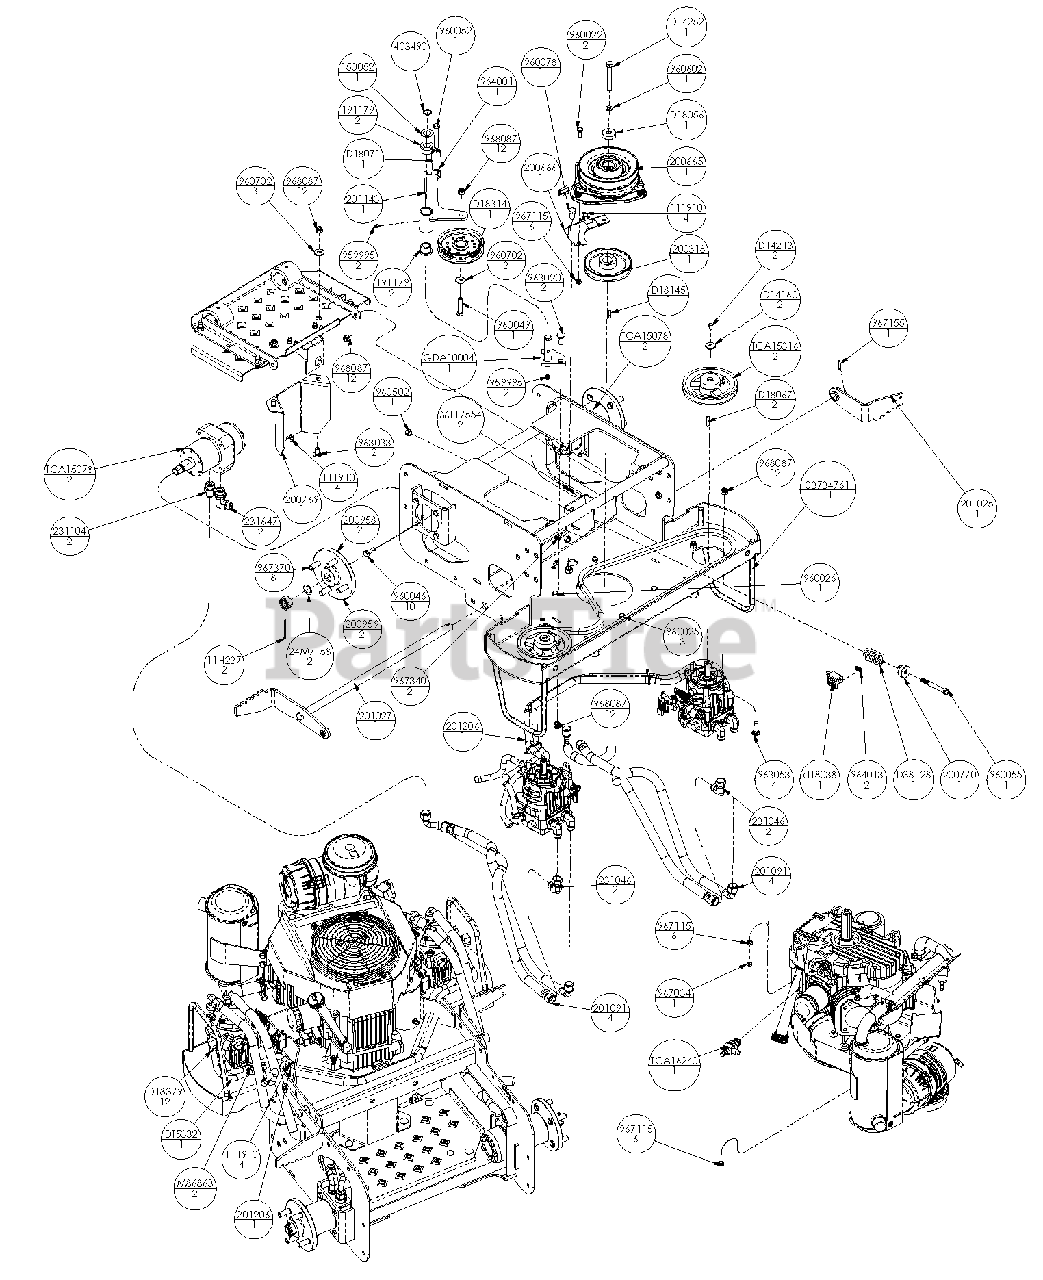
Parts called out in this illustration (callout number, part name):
1	HOSE, 3/8 SAE30R7 FUEL & OIL
2	WASHER, .250 WIDE HEAVY FLAT Y
3	BOLT, M6 X 1.00 X 10 HEX 8.8 Y
4	BOLT, 7/16-20X3.00 HEX 5 Y
5	SWITCH (N.0.)
6	SPACER, .468 X 1.38 X .375 Y
7	KEY, M5 X M5 X M30 RD
8	SPRING, EXT .900X.135X4.50 Y
9	PULLEY, V-BELT 4.00X.379 W/BRG
10	CLAMP, HOSE - 1/2" PINCH
11	SPRING, COM 1.22X.162X2.50 Y
12	WLDT, PIVOT IDLER MOUNT
13	DECAL, WARNING - HOT SURFACES
14	FTG, TUN 3/8 HOSE
15	MOTOR, WHEEL HGM-12P-7172
16	ASSY, PUMP PULLEY W/SET SCREW
17	FITTING, OIL DRAIN
18	PIN, COT .125 X 2.00 EXTP Y
19	CABLE TIE, .15 X 8.50
20	BUSHING, MACH .750X1.25X.048 Y
21	BRG, FLG .750 X 1.00 X .750 BRNZ
22	PULLEY, V-BELT 4.78PD X 1.000 W/KEY
23	CLUTCH ASSY, OGURA
24	PLATE, CLUTCH DOG
25	COVER, OPC
26	WASHER, SPRING Y
27	WHEEL HUB, MACHINED
28	ASSY, REAR WHEEL HUB (Includes 20958 & 967370)
29	BELT, HA 68.2 EL AMD OHR
30	WLDT, RH BRAKE ARM
31	WLDT, LH BRAKE SHAFT
32	HOSE, HYD 1/2 X 26 1/2 EZFLEX
33	WLDT, FRAME 34
34	WLDT, IDLER PIVOT
35	ABRASION SLEEVE
36	FTG, ADP MJIC-FSWJIC 6500-08-08
37	FTG, ADP 3/4-16FJIC X 7/8-14MOR
38	FTG, ADP JIC-ORB 2062-10-8S
39	SHIM, .020X.787X1.102
40	SNAP RING, .750 X .042 EXT
41	FTG, 1/4-28 STRGT GREASE ZERK
42	BOLT, 5/16-18 X .750 HEX 5 Y
43	BOLT, 5/16-18 X 1.50 HEX 5 Y
44	BOLT, 5/16-18 X 1.75 HEX 5 Y
45	BOLT, 3/8-16 X 1.00 HEX 5 Y
46	BOLT, 3/8-16 X 1.75 HEX 5 Y
47	BOLT, 3/8-16 X 2.50 HEX 5 Y
48	BOLT, 3/8-16 X 3.25 HEX 5 Y
49	BOLT, 7/16-14 X .750 HEX 5 Y
50	NUT, 3/8-16 STD HEX GR5 Y
51	WASHER, .375 MED SPRG LOCK Y
52	WASHER, .375 REG FLAT Y
53	BOLT, 3/8-16 X 1.00 CRG 5 Y
54	Bolt,3/8-16x3/4 Car Gr5 LNnk
55	BOLT, 3/8-16 X 1.25 CRG 5 Y
56	NUT, 3/8-16 JAM GR5 Y
57	LOCKNUT, 10-24 NYLOC Y
58	NUT, 5/16-18 JAM GR5 Y
59	LOCKNUT, 5/16-18 NYLOC Y
60	PIN, ROL .156 X 1.00
61	SCREW, 10-24 X .625 PAN PHL MAC Y
62	BOLT, 1/2-20 x 1.66 SPC
63	LOCKNUT, 3/8-16 NYLOC Y
64	KEY, .250 X .250 X .995 TPR
